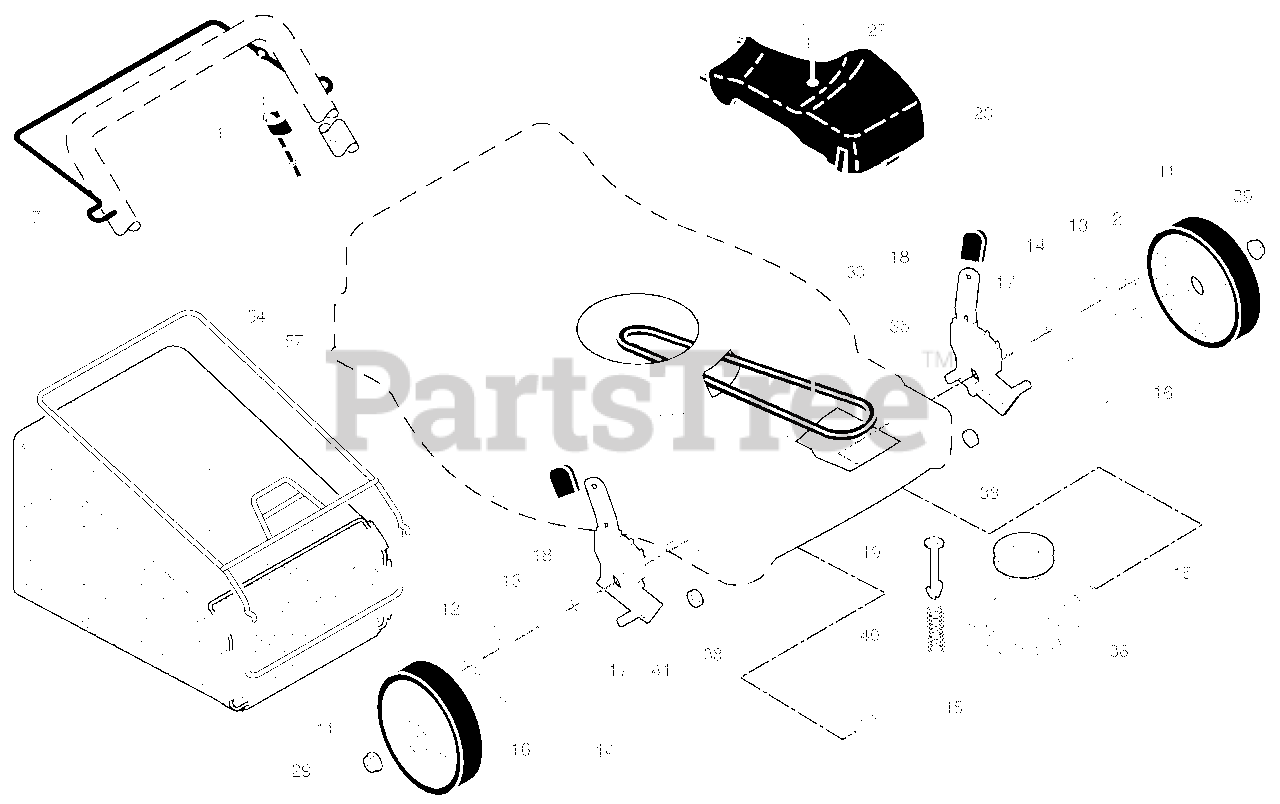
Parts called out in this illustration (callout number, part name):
1	CABLE, DRIVE CONTROL
7	Control Bar, Drive
11	WHEEL AND TIRE ASSEMBLY-FRONT
14	Dust Cover
15	Pawl, Drive
16	Washer, Flat 3/8
17	BEARING
18	Selector Knob
19	Retainer, Spring
27	Pan Head Tapping Screw #10-24
28	DRIVE COVER
29	Nut, Hex
33	DRIVE BELT
35	KIT,WHEEL ADJUSTER, RH (INCLUD
36	Gear Case Assembly, Complete
38	Locknut, Hex 1/4-20
41	KIT,WHEEL ADJUSTER, RH (INCLUD
57	BAG FRAME
